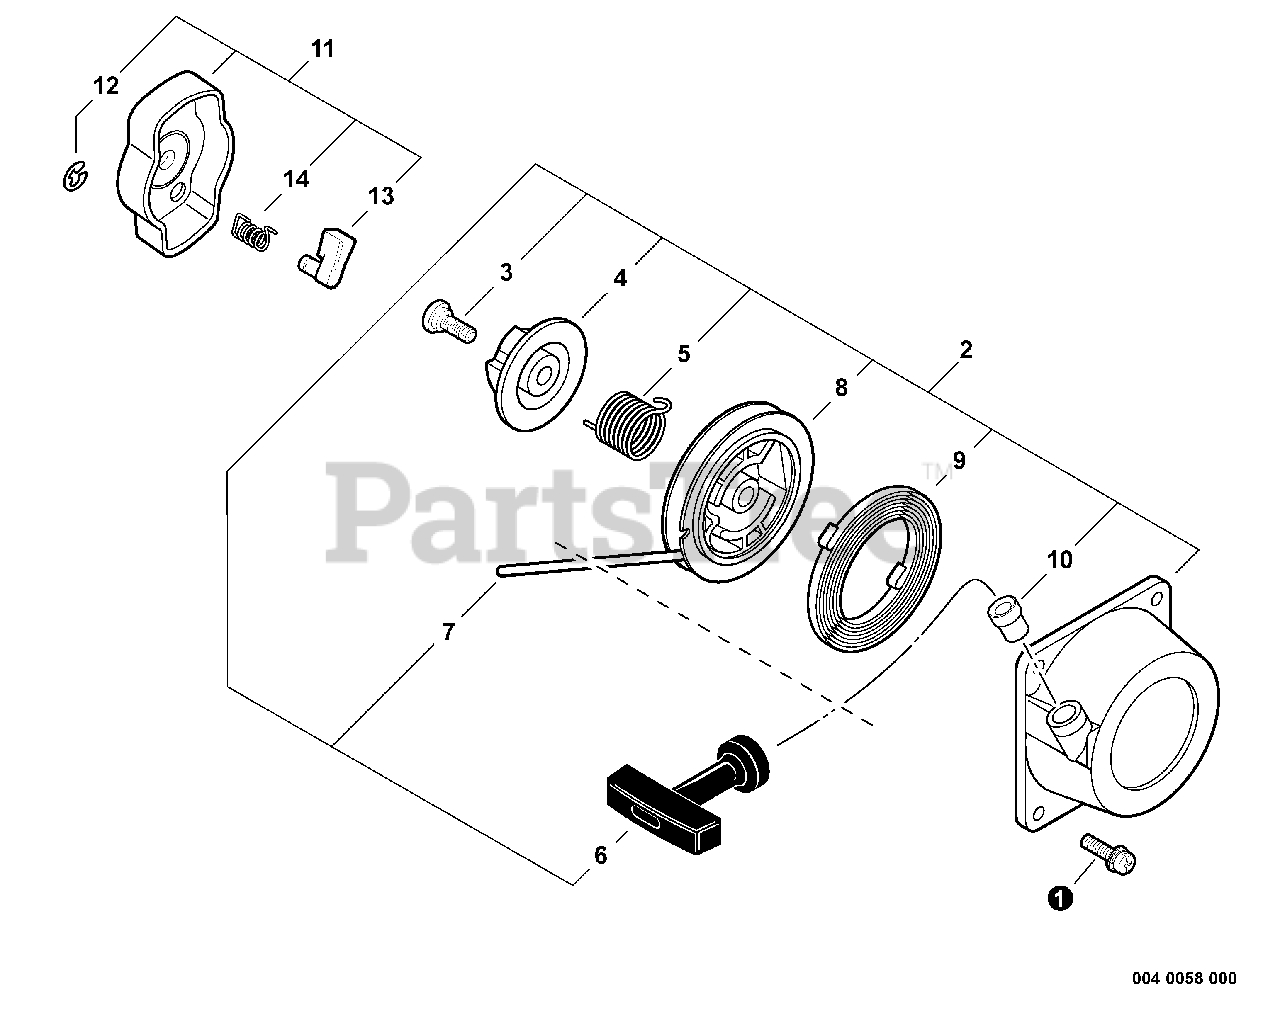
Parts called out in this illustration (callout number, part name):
1	SCREW - 4X16
2	STARTER ASSY
3	SCREW
4	PLATE, CAM
5	SPRING, DAMPER
6	GRIP, STARTER
7	ROPE, STARTER
8	REEL, ROPE
9	SPRING, REWIND
10	GUIDE, ROPE
11	STARTER PAWL ASSY
12	RING, RETAINING - 4
13	PAWL, STARTER
14	SPRING, RETURN
